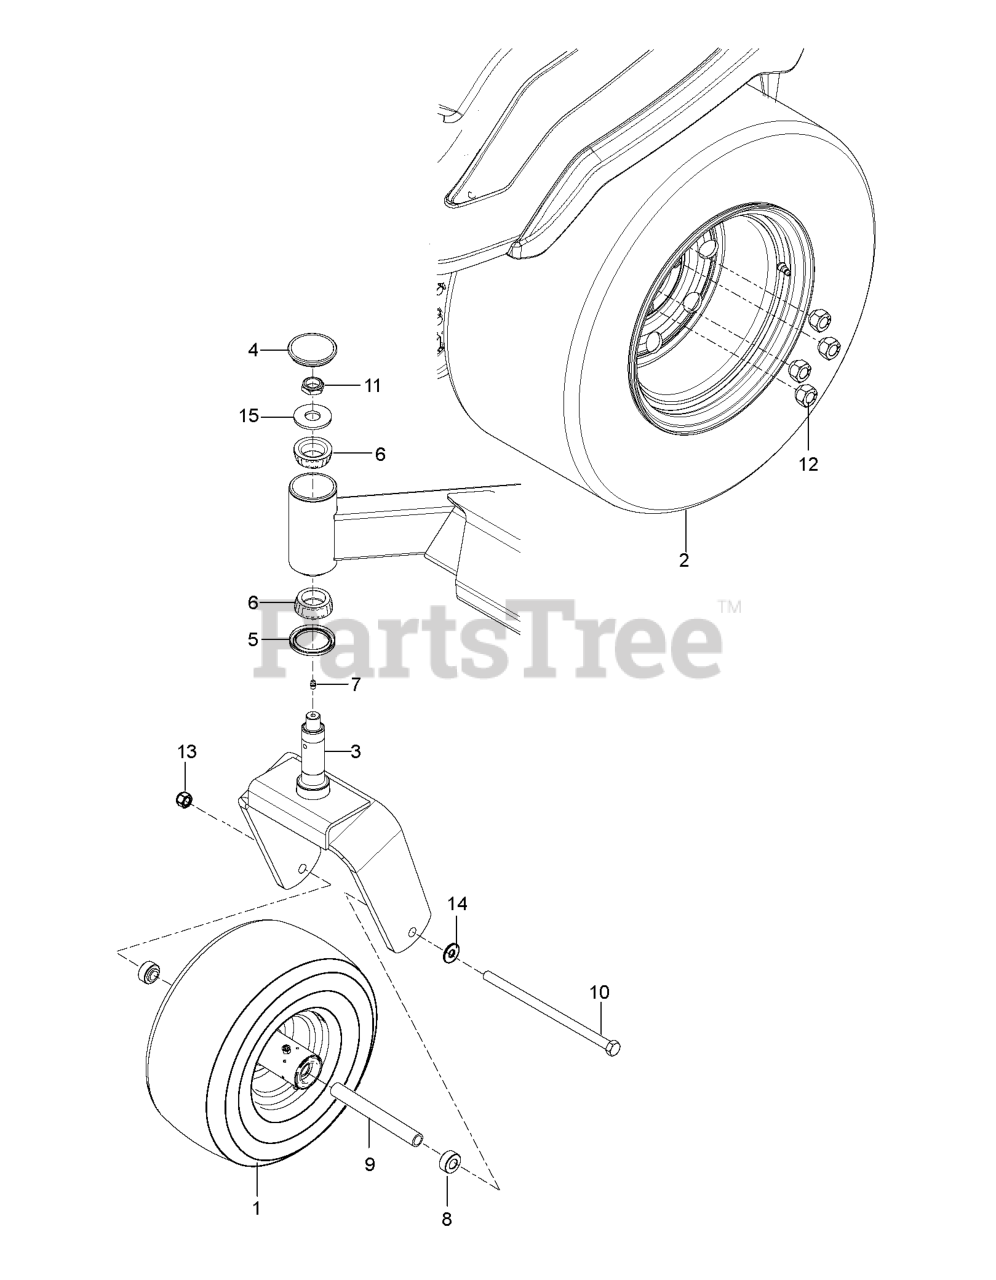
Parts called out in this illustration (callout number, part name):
1	FRONT TIRE ASSY
2	WHEEL/TIRE.ASM SILV 23X10.5-12
3	FORK, CASTER, ORG
5	SEAL, BEARING
6	CONE, LM67048
7	ZERK
8	SPACER.AXLE
9	SPACER.HUB
10	HEX SCREW 1/2-13 X 9.5 GR5
11	NUT, 3/4-16 HEX THIN NYLOC ZD
12	NUT.1/2-20.UNF-2B.GR.8.YL
13	NUT, 1/2-13 HEX FLG NYLOC ZD
14	WASHER 1/2" FLAT
15	WASHER, 3/4 HARDENED
